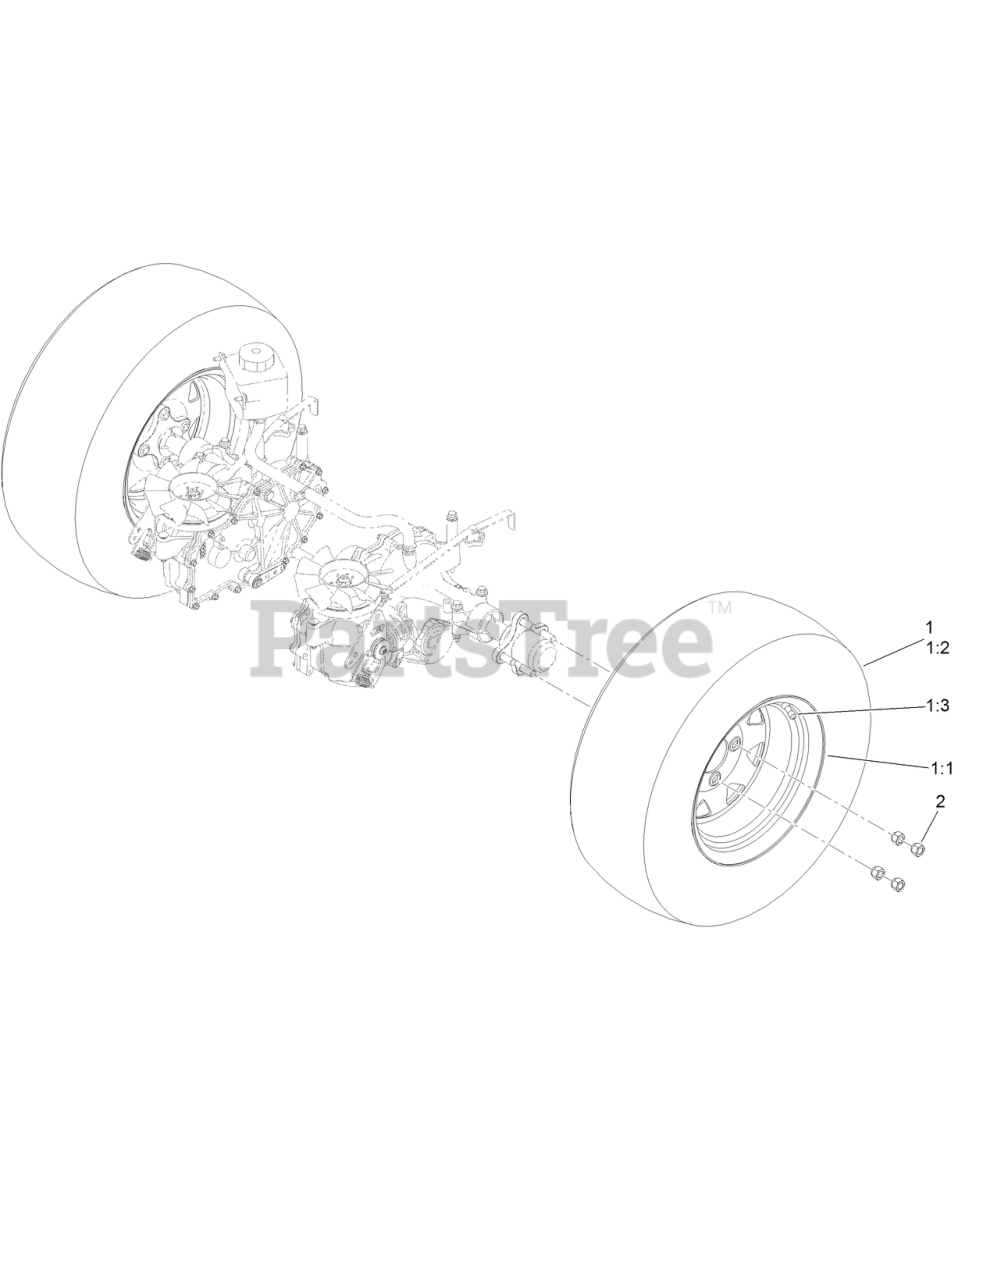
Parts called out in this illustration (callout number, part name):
1	WHEEL AND TIRE ASM
1:2	TIRE
2	NUT-LUG
